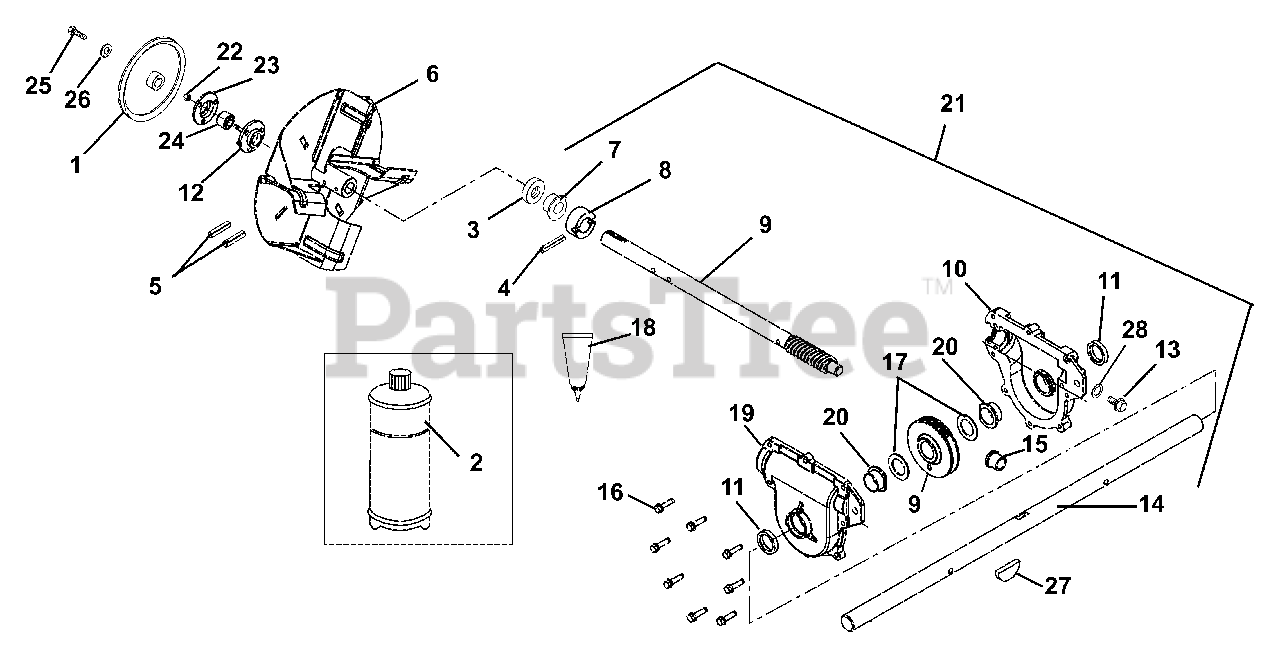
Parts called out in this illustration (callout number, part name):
1	PULLEY, 4L W/HUB, .87 X 8.5
2	ARIENS 16 OZ.BOTTLE OF L2 LUBE
3	SEAL-OIL .875X1.375X.25 RBR OD
4	PIN-GRV .250X1.50 TP E
5	PIN-ROLL .250X1.75
6	IMPELLER-14" 4 BLADE
7	BSHG-FLG .876 X 1.500 X .750
8	THRUST COLLAR, .875" ID
9	ASSY, WORM SHAFT & GEAR
10	GEARCASE, ALUMINUM, LH
11	SEAL-OIL 1.000X1.375X.250
12	BEARING FLANGE
13	SCR-TAP .38-16X.75 ROLOK YZ WX
14	SHAFT, RAKE-26"
15	BSHG-FLG .629 X 1.000 X .750
16	@SCR-TAP .25-20X1.00 HWH TR YZ
17	WSHR-HRD-THRS 1.007X1.542X.062
18	LOCTITE 518 GASKET--6ML TUBE
19	GEARCASE, ALUMINUM, RH
20	BSHG-FLG 1.003X1.5X.625
21	GEARCASE ASS'Y - 26" ALUMINUM
22	@NUT-LK-CTR .25-20 YWZC
23	BEARING FLANGE
24	BRG-BALL .876 X 1.750 X .50
25	BLT-HEX .31-24X1.0 GR5 YZ EP80
26	WSHR-LK .312X.097 HVY YWZC
27	KEY-WDRF .25X.875X.375 SAE A
28	WSHR-FIBER .437X.656X.032
